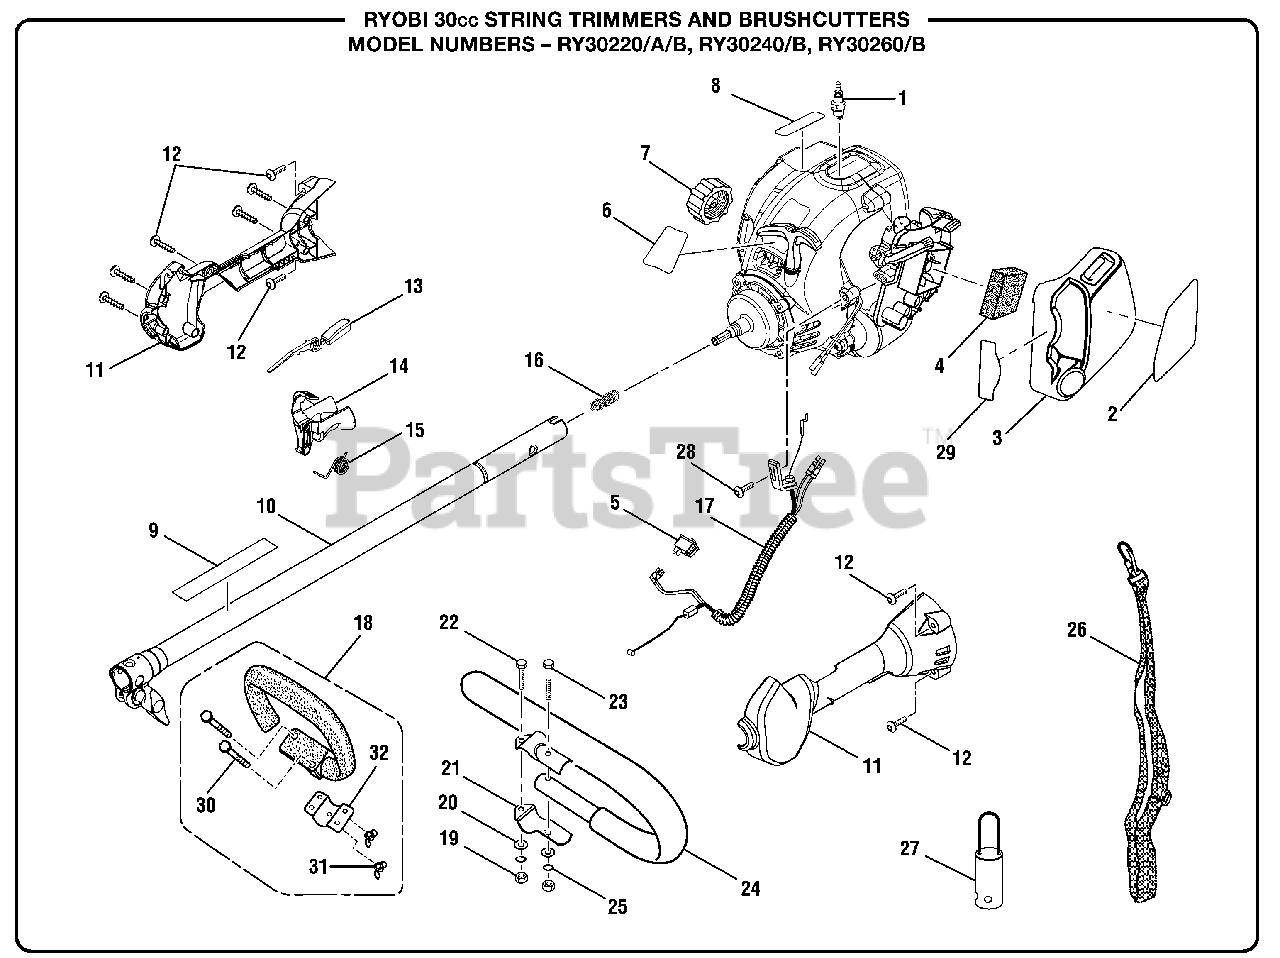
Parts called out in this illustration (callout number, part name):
1	SPARK PLUG
2	STARTING LABEL
3	AIR BOX COVER
4	AIR FILTER ELEMENT
5	SWITCH (MOMENTARY CONTACT)
6	MODEL LABEL (CS30)
7	FUEL CAP ASSEMBLY
8	LOGO PLATE
9	WARNING DECAL (CS30 AND SS30)
10	UPPER BOOM ASSEMBLY
11	CONTROL HANDLE ASSEMBLY
12	SCREW (10-14 X 1 in.)
13	TRIGGER LOCK
14	TRIGGER
15	TORSION SPRING
16	COMPRESSION SPRING
17	THROTTLE AND LEAD ASSEMBLY
18	FRONT HANDLE ASSEMBLY (CS30 AND SS30)
19	HEX NUT (1/4-20) (BC30)
20	WASHER (BC30)
21	HANDLE BAR CLAMP (BC30)
22	BOLT (1/4-20 X 1 in. HEX HD.) (BC30)
23	BOLT (1/4-20 X 1-1/2 in. HEX HD.) (BC30)
24	"J" HANDLE AND GRIP (BC30)
25	LOCK WASHER (BC30)
26	SHOULDER STRAP (BC30)
27	HANGER CAP
28	SCREW (10-24 X 7/8 in.)
29	CHOKE LABEL
30	BOLT (M5 X 30 mm HEX HD.) (CS30 AND SS30)
31	WING NUT (M5)
32	HANDLE BAR CLAMP (CS30 AND SS30)
